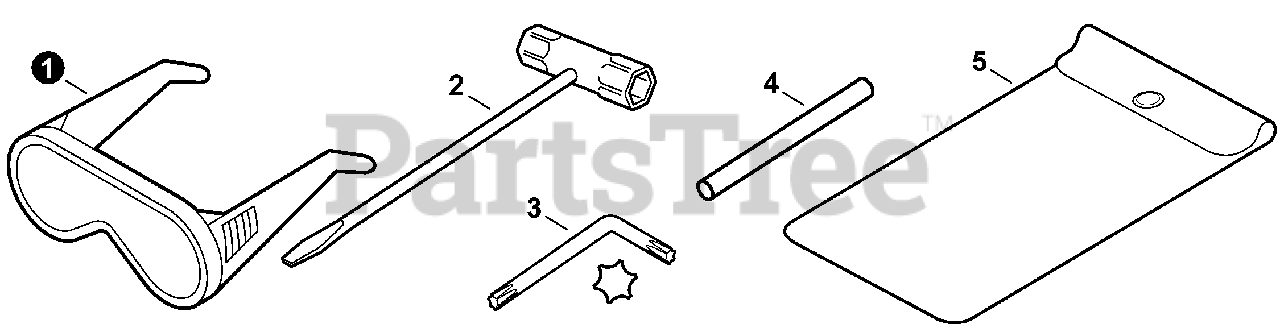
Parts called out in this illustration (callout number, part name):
1	GLASSES, SAFETY
2	T-WRENCH 17x-19 L200
3	WRENCH, T27 80×30
4	TOOL, LOCKING 5×120 MM
5	BAG, TOOL
